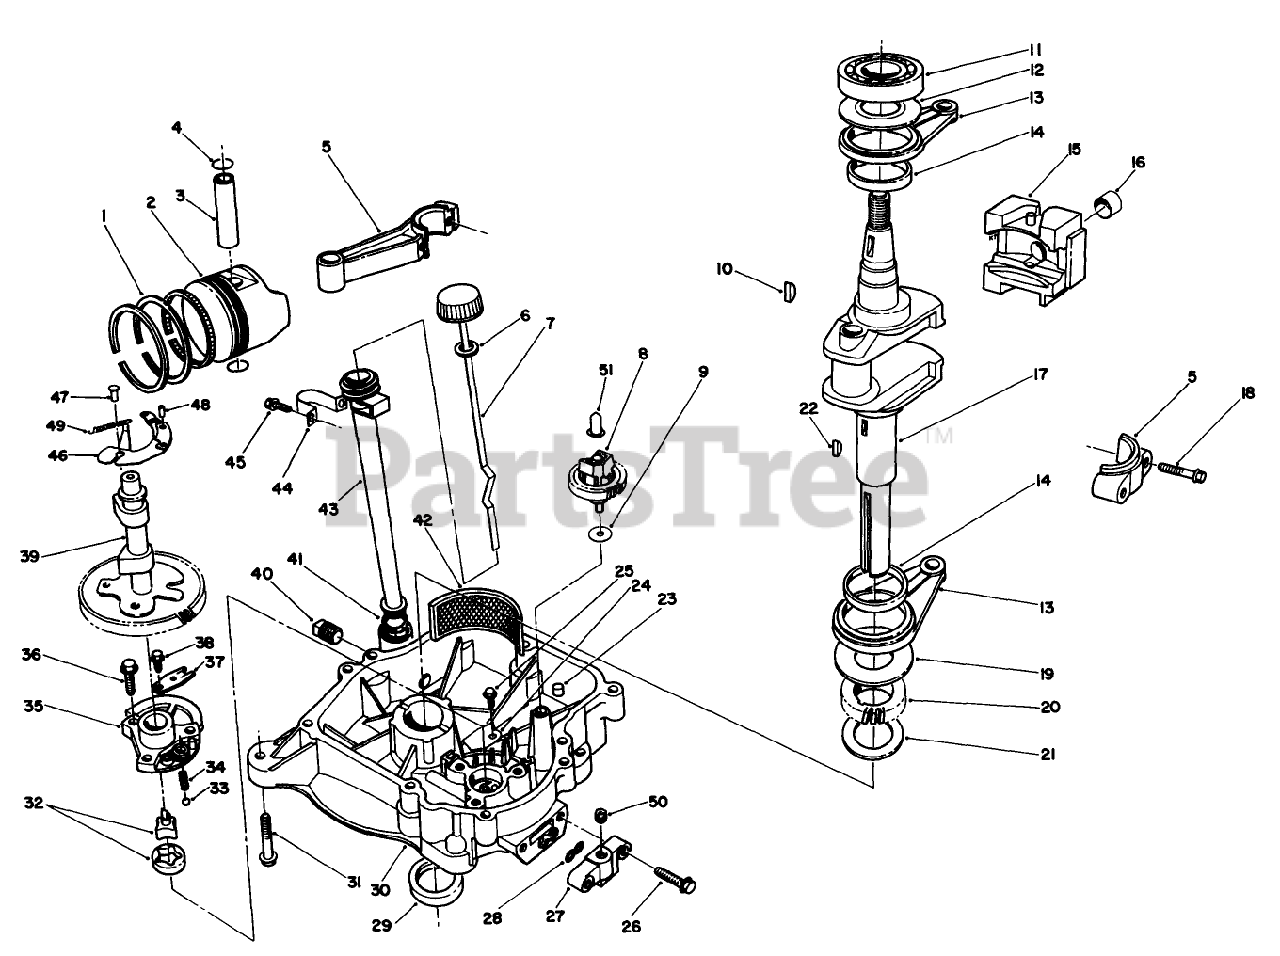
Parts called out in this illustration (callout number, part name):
1	Piston Ring Set
3	Pin-Piston
4	Ring-Snap
5	Connecting Rod Ass-y-Standard (includes item 44)
8	Governor ASM
11	Ball Bearing
13	Rod Incl #8
14	Bearing
15	Weight Complete (includes item 133)
16	Bushing
17	Crankshaft
21	Shim (1.18)
29	Oil Seal
31	Bolt-Flanged (8X45)
32	Pump ASM-Oil
35	Cover-Pump
36	Bolt-Flanged (8X25)
38	BOLT-FLANGED (6X10)
39	Camshaft
41	O-RING (16mm)
42	Filter-Oil
46	Decompressor
